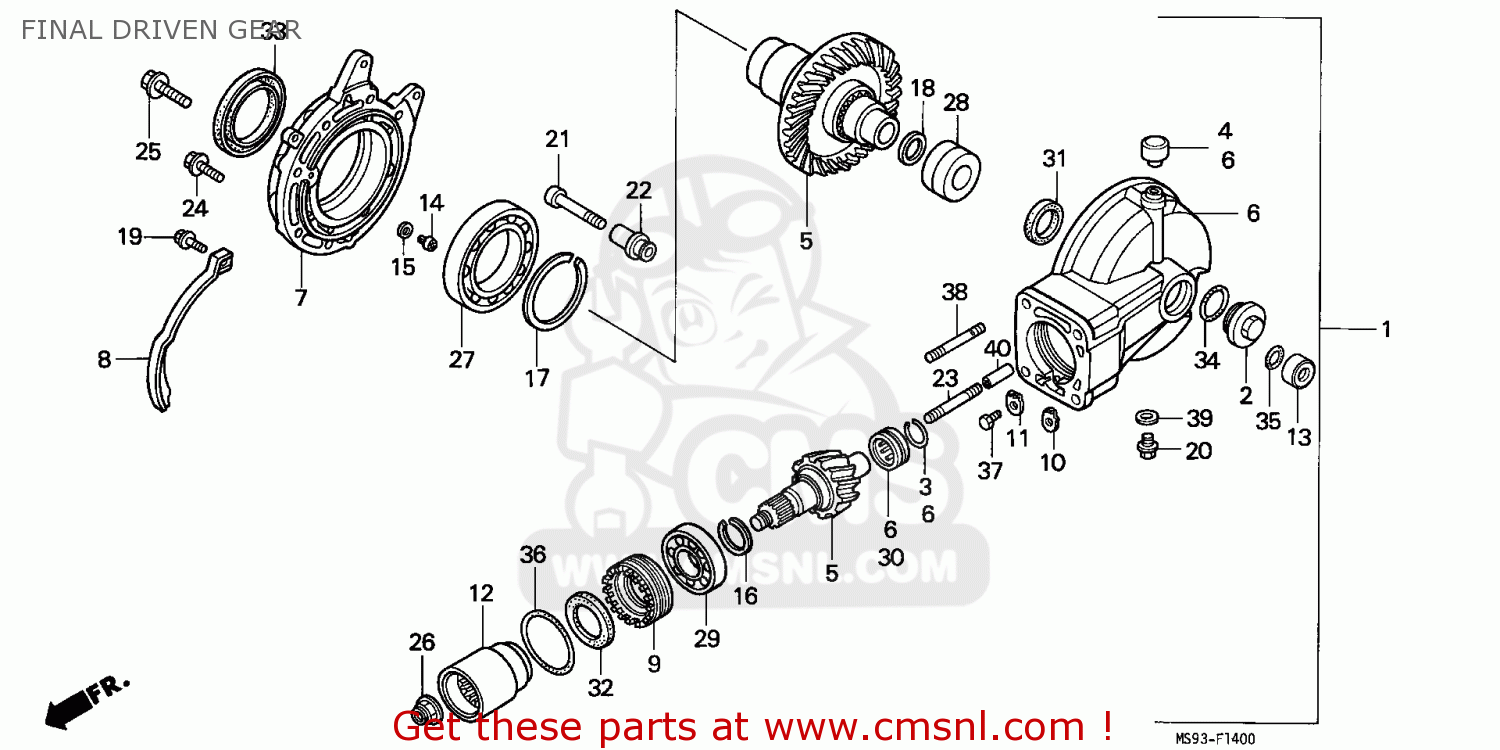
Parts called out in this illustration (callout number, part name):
1	GEAR ASSY.,FINAL
2	CAP,GEAR CASE OIL
3	RING,STOPPER
4	CAP,BREATHER
5	GEAR SET,FINAL
6	CASE SET,FINAL
7	COVER,GEAR CASE
8	PLATE,DUST GUARD
9	RETAINER,BEARING
10	LOCK A BEARING AD
11	LOCK B BEARING AD
12	JOINT,PINION
13	COLLAR,RING GEAR
14	PIN,RING GEAR STO
15	SHIM A,STOPPER PI
16	SHIM A,PINION GEA
17	SHIM A,RING GEAR
18	SHIM A,SHAFT (1.7
20	BOLT,PLUG,14MM
21	BOLT,DRIVE PIN
22	PIN,DRIVE
23	BOLT,STUD,10X42
24	BOLT,FLANGE,8X27
25	BOLT,FLANG 10X35
26	NUT,HEX.,16MM
27	BEARING,RADIAL BA
28	BEARING,RADIAL BA
29	B/BRG RAD N/COM
30	NEEDLE BRG
31	OIL SEAL,38X50X8
32	OIL SEAL,39X51X7
33	OIL SEAL,85X110X7
34	O RING, 30.8M/M
35	O-RING,29.7X1.9
36	O-RING,58.5X3.5
37	BOLT,HEX 6X12
38	BOLT,STUD,10X32
39	WASHER,PLUG DRAIN 14
40	PIN D,DOWEL,12X20
